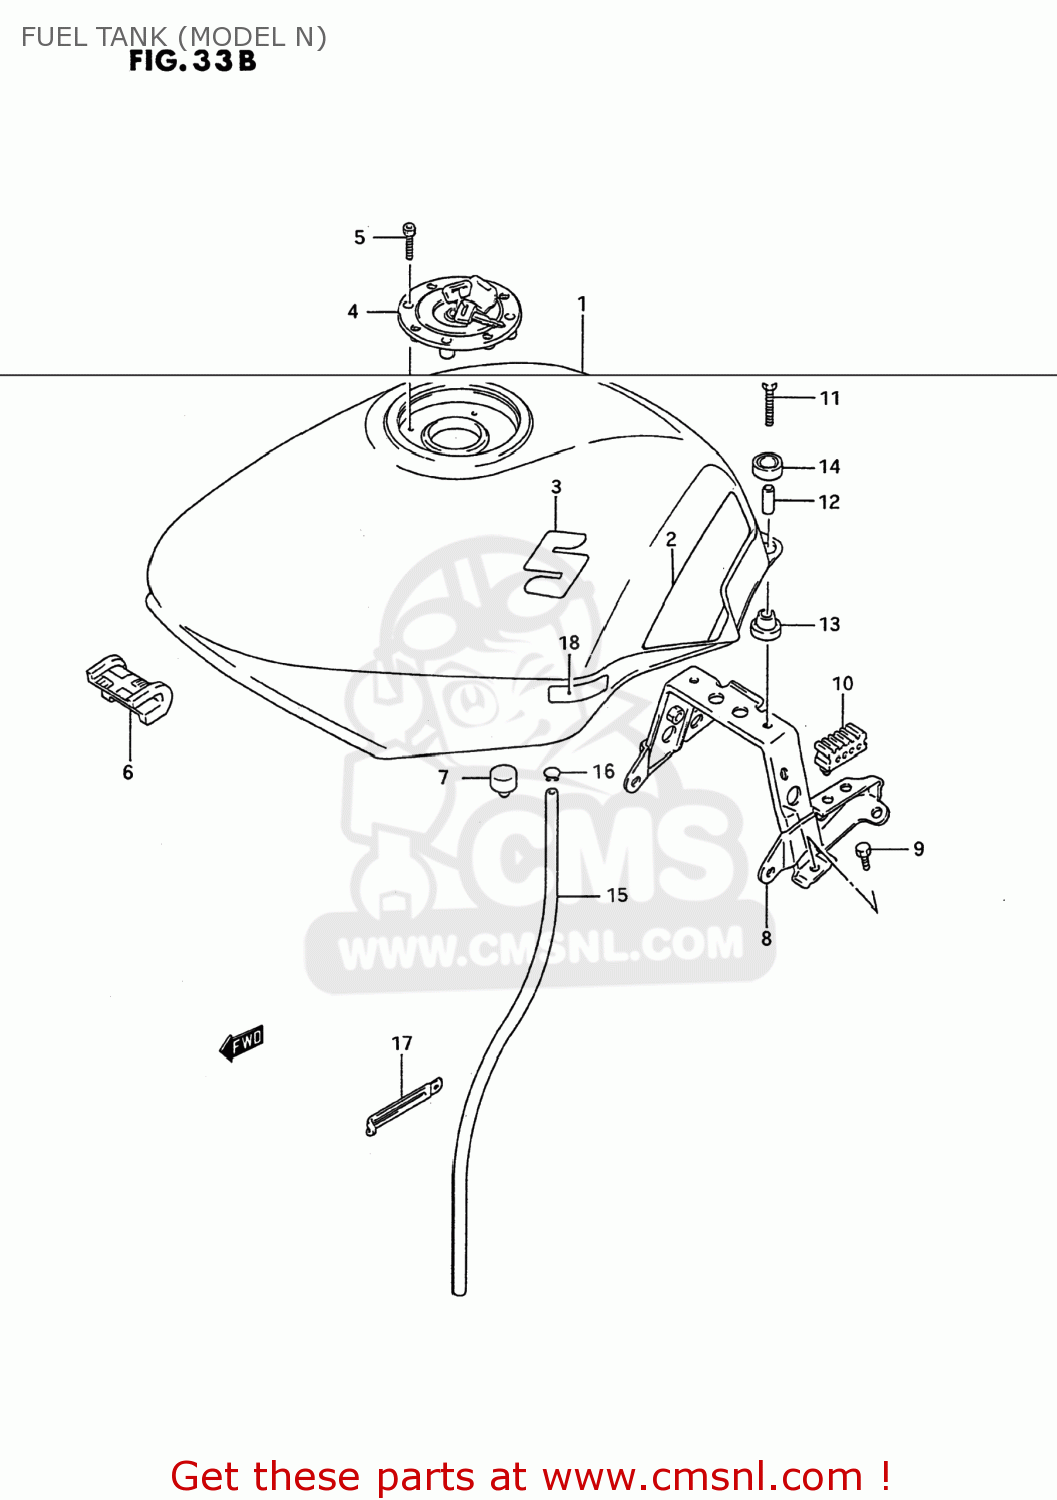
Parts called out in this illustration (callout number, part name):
1	TANK ASSEMBLY,FUEL
2	TAPE SET,FUEL TANK
3	EMBLEM,FUEL TANK
4	CAP SET,FUEL TANK
5	BOLT(5X20)
6	CUSHION,FUEL TANK FR
7	CUSHION
8	BRACKET,FUEL TANK RR
9	SCREW
10	CUSHION,SEAT(40X20X15)
11	BOLT
12	SPACER
13	CUSHION
14	CUSHION
15	HOSE,FUEL TANK WATER DRAIN
16	CLIP
17	CLAMP(L:120 T:1.0)
18	PROTECTOR,FUEL TANK,LEFT
